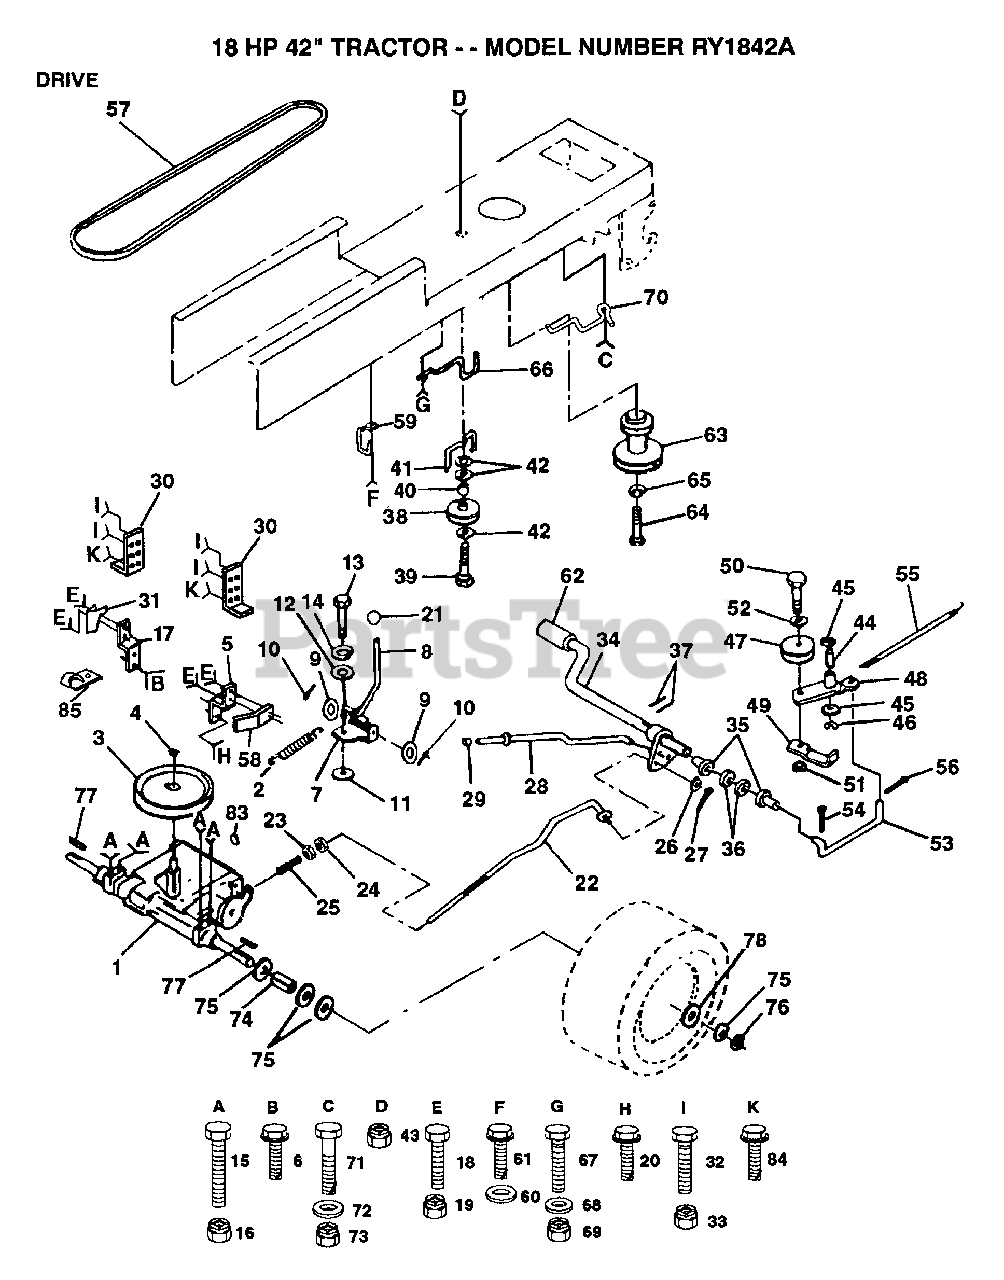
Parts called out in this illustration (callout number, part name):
3	"PULLEY,TRANSAXLE"
5	STRAP TORQUE
6	SCREW
8	SHIFT ROD
9	WASHER
10	PIN COTTER 1/8
11	WASH-SHFT PLT LT
12	WASHER LT
14	LOCKWASHER
15	BOLT
17	STRAP TORQUE
20	SCREW
21	KNOB T (1/2-HOLE)
22	BRAKE ROD
23	NUT
24	NUT
25	SPRING ROD LT
26	WASHER
27	COTTER PIN
28	BRAKE PARK ROD
29	PLUNGER CAP T
30	TRANSAXLE MTG BKT
31	"KEEPER,BELT LH"
32	BOLT
35	NYLON BEARING
36	WASHER LT
38	PULLEY.IDLER.FLAT
39	BOLT
40	SPACER T
41	BELT KEEPER LT
42	WASHER
44	"LY, BEARING"
45	WASHER LT
46	KLIP RING
48	ARM IDLER
49	RETAIN BELT
52	WASHER
53	"LINK, CLUTCH T"
54	COTTER PIN
55	"SPRING, RETURN LT"
56	COTTER PIN
57	BELT-V
58	"KEEPER,BELT RH"
60	WASHER
61	SCREW
62	PEDAL COVER T
64	BOLT
65	LOCKWASHER
66	KEEPER.BELT.ENG.L
67	BOLT
68	WASHER
70	KEEPER BELT ENG
71	BOLT
72	WASHER
74	SPACER LT
75	WASHER
76	E-RING LT
77	SQUARE KEY
78	WASHER
84	SCREW
85	CLIP T
